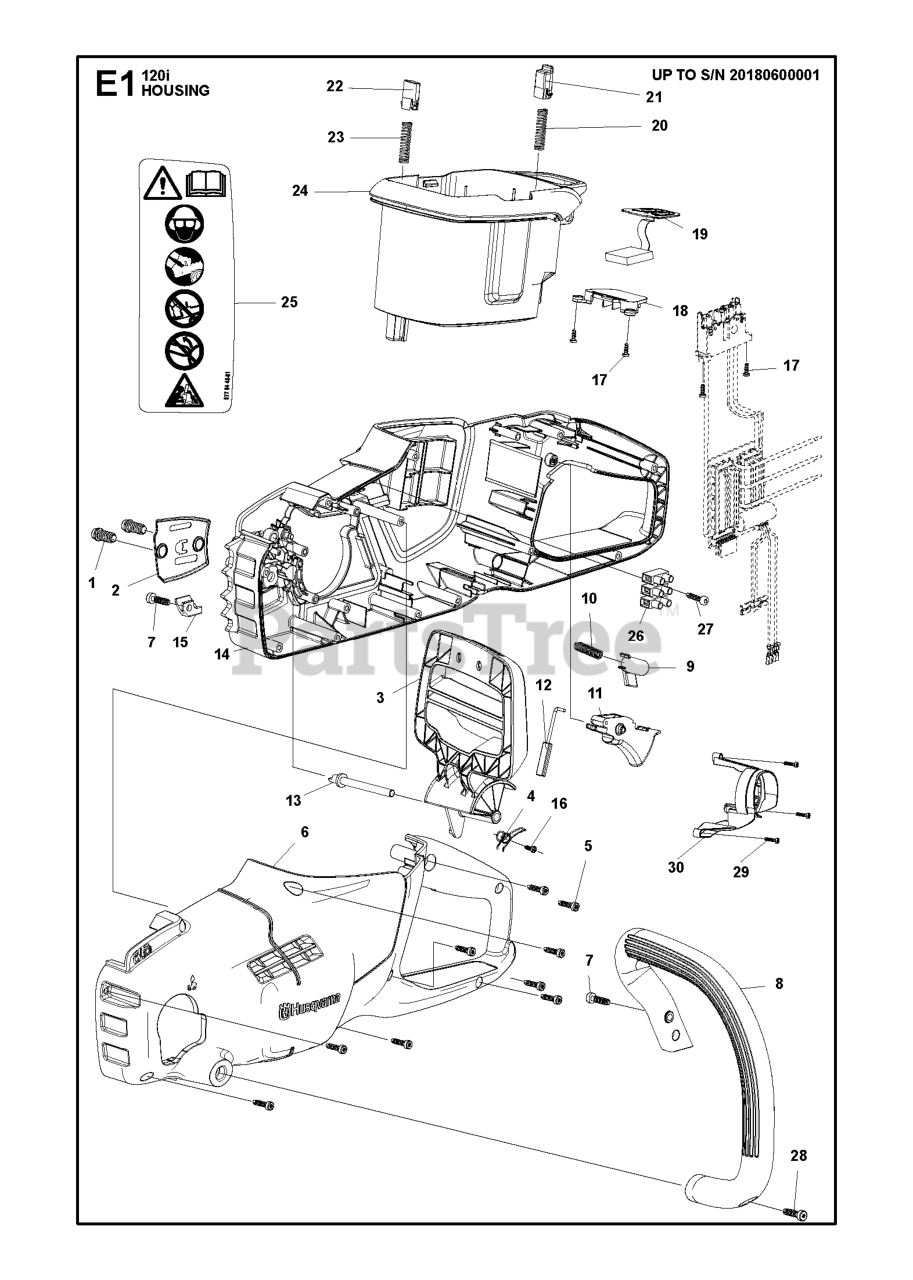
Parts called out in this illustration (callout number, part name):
1	SCREW ST8X16
2	MOUNTING PLATE BAR
3	BRAKE HAND GUARD
4	SPRING BRAKE CUT OFF POWDER
5	SCREW ST4X16
6	HOUSING LEFT - PAINTING
7	SCREW ST4.8X18
8	FRONT HANDLE
9	BUTTON LOCK OFF
10	SPRING LOCK OFF BUTTON
12	LEVER TRIGGER
13	PIVOT HAND GUARD
14	HOUSING RIGHT ASSEMBLY
15	CHAIN CATCHER
16	SCREW SCREW MT3X10 36V
17	SCREW ST3X8
18	BRACKET KEY PAD
19	KEYPAD CHAINSAW
20	SPRING PUSH BUTTON
21	PUSH BUTTON
22	PUSH BUTTON FRONT
23	SPRING PUSH BUTTON
24	BATTERY BOX
26	CONNECTOR SMALL
27	SCREW ST3X16
28	SCREW
29	SCREW ST4X12
